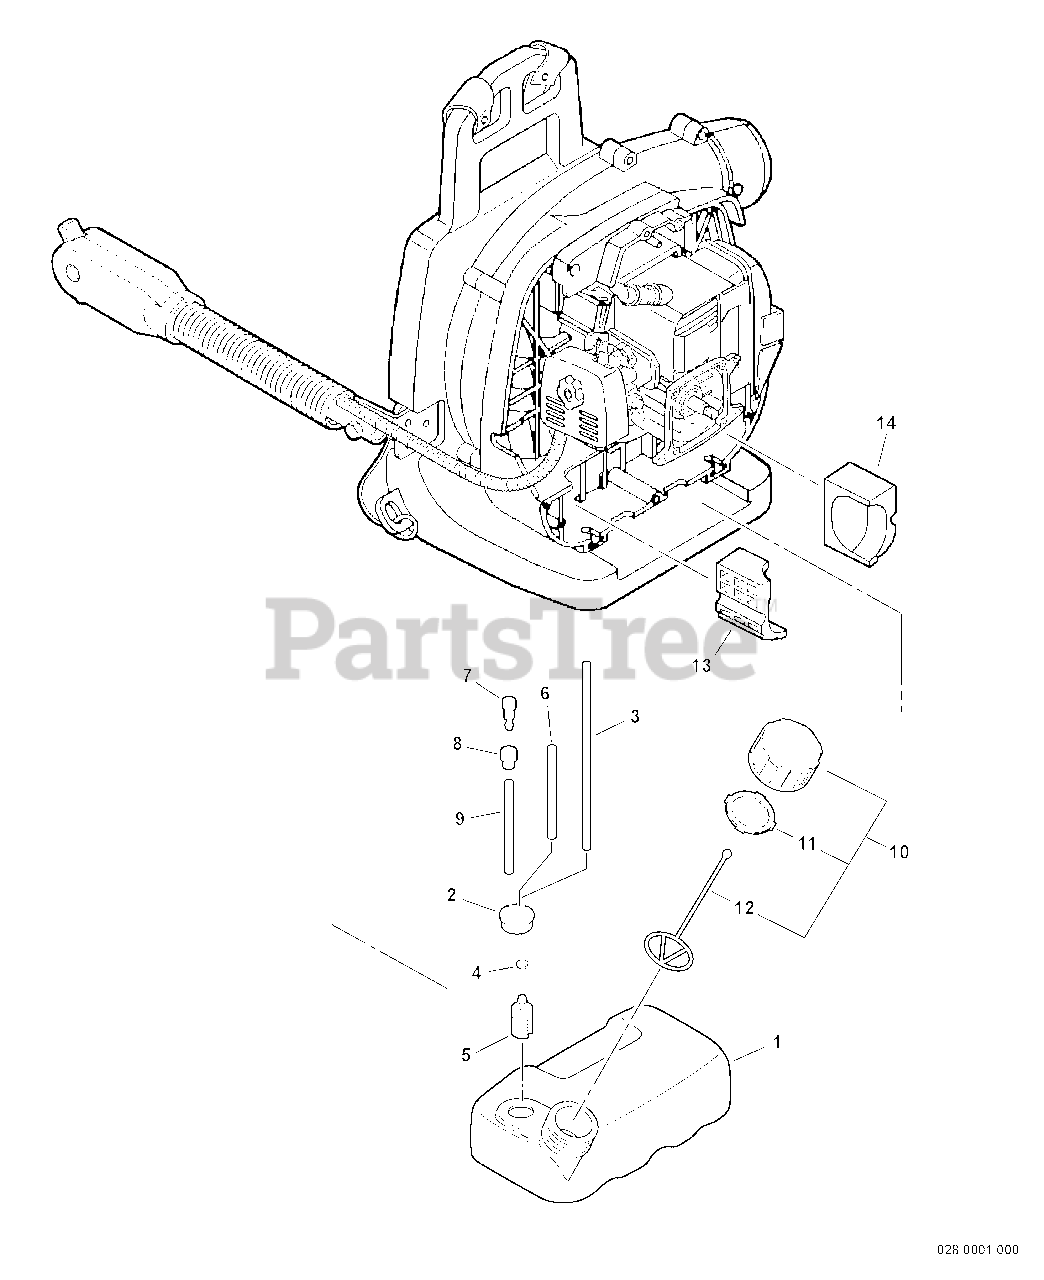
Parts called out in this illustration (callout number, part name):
1	TANK, FUEL
2	GROMMET
3	PIPE - 3X6X200 -- BLACK
4	CLIP - 6.5
5	FILTER, FUEL
6	PIPE - 3X6X100 -- CLEAR
7	VENT, FUEL TANK
8	COVER, VENT
9	PIPE - 3X6X100 -- BLACK
10	CAP ASSY - ORANGE
11	GASKET, CAP
12	CONNECTOR, CAP
13	CUSHION, FUEL TANK - LEFT
14	CUSHION, FUEL TANK - RIGHT
